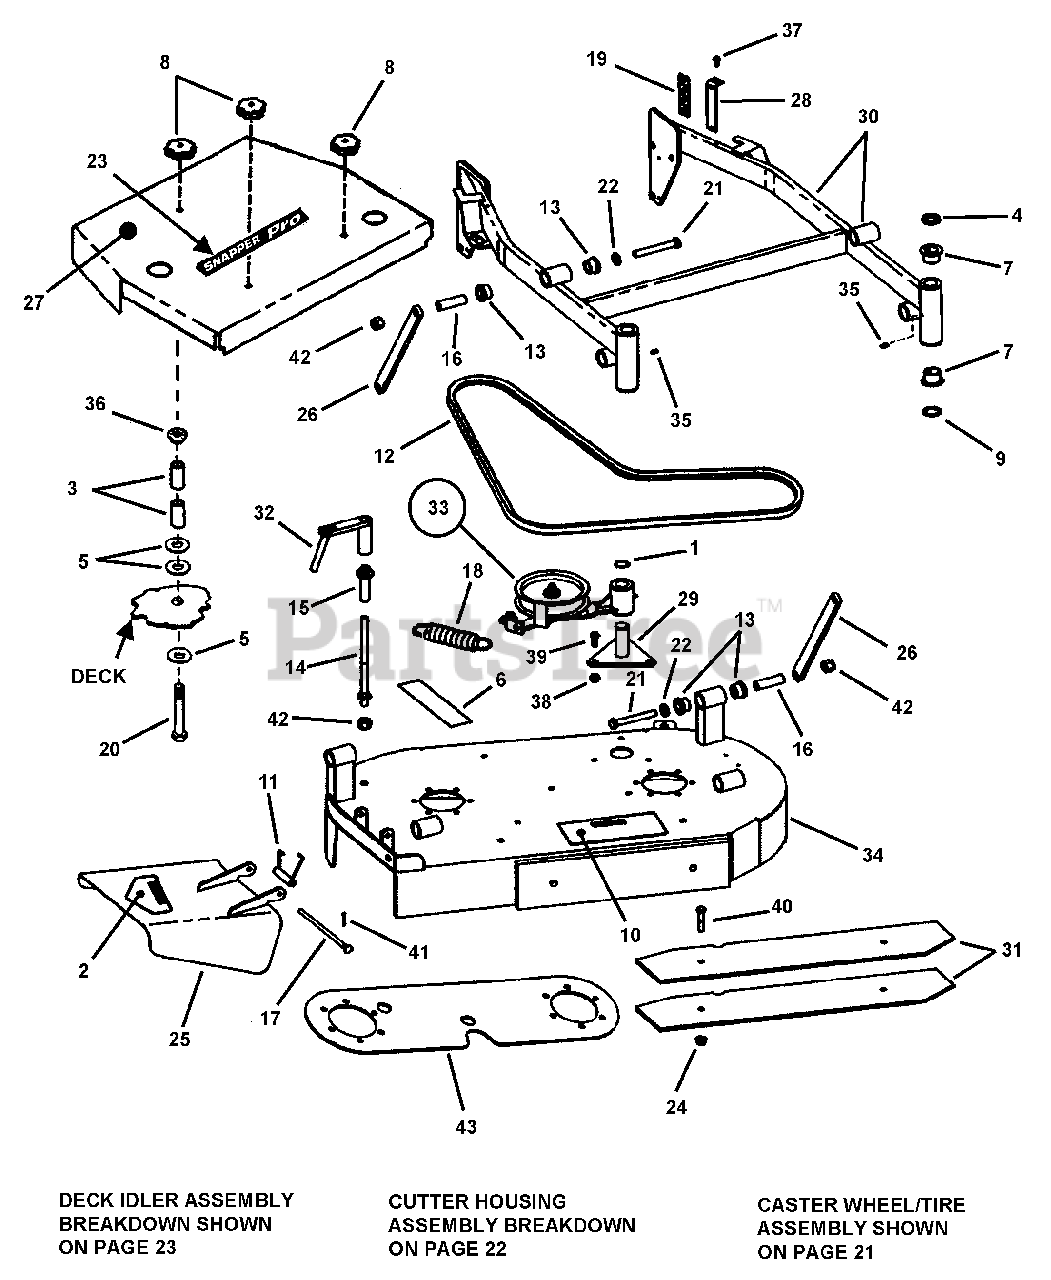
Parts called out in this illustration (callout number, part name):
1	SNAP-RING, 1" External
2	DECAL, Warning (CPSC Cut Finger)
3	SPACER
4	SPACER, 1" x 1 3/8 x .30" (PM)
5	WASHER, 3/8" I.D. Flat
6	DECAL, Warning
7	BUSHING, Caster
8	KNOB, Hood
9	BUSHING, 1"
10	DECAL, Caution- Operator Instruction
11	SPRING, Chute
12	V-BELT, Deck Drive 36" (Nominal Effective Length 84.80")
13	BUSHING, Suspension
14	STUD, Lift, 1/2-13 Thread, Both Ends
15	LIFT WASHER (Weldment)
16	SLEEVE, Suspension
17	HINGE PIN, Chute
18	SPRING, Idler
19	DECAL, Height-of-Cut
20	SCREW, 5/16-18 x 4-1/2" Hex Head Cap, Grade 5
21	BOLT, 1/2-13 x 3-3/4" Grade 5
22	WASHER, 1/2" Flat
23	DECAL, Snapper Pro
24	NUT, 3/8-16 HEX SERRATED FLANGE
25	DEFLECTOR, Chute Red
26	ARM, Suspension
27	COVER, 36"
28	BRACKET, Height-of-Cut
29	PIVOT, Idler (Weldment)
30	FRAME, 36" Adjustable (Weldment)
31	PLATE, Ballast
32	ASSEMBLY, Crank
33	ASSEMBLY, Idler Arm 36"
34	WELDMENT, Deck, Adjustable Height (Red)
35	FITTING, Lube 1/4-28 Straight
36	NUT, 5/16-18 Hex Flange Lock, Grade 5
37	SCREW, 1/4-20 x 5/8" Hex Washer Self-Tap
38	NUT, 3/8-16 HEX NYLON LOCK
39	BOLT, 3/8-16 X 1" GD5 CZ
40	BOLT, 3/8-16 X 2, GD5, CZ
41	PIN, 3/32 x 1" Cotter
42	NUT, 1/2-13 Nyloc
43	PLATE, Stiffener (7 Gage)
